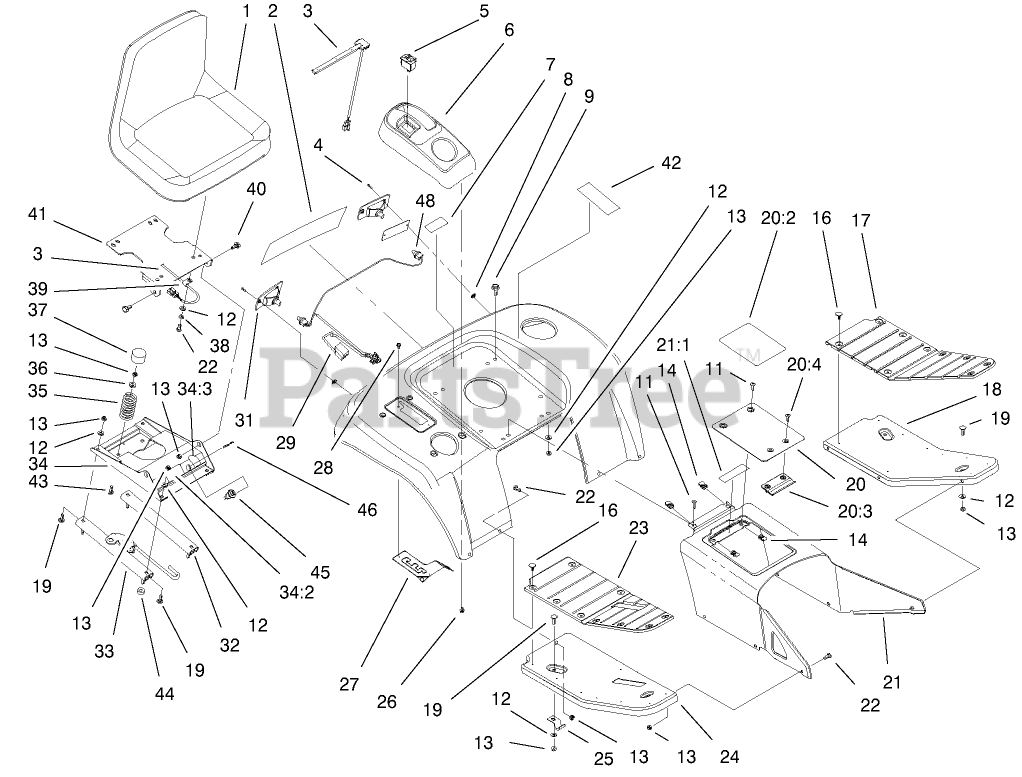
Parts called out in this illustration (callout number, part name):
3	SWITCH-SEAT
4	SCREW-PPH
5	SWITCH-CRUISE
6	POD-CONTROL
6	POD - CONTROL INT'L
7	DECAL - USA
8	NUT-SPEED
9	SCREW-HHF
11	SCREW-HH
12	WASHER-PLAIN
13	NUT-LOCK, NI
16	FASTENER-PANEL
17	PAD-FOOTREST, LH
18	FOOTREST-LH
19	SCREW-CARR
20	TUNNEL COVER ASM
20:2	DECAL-DANGER
20:2	DECAL - DANGER
20:3	RETAINER-COVER
20:4	SCREW-PPH
21	TUNNEL ASM
21:1	DECAL - WARNING
21:1	DECAL-DANGER
22	SCREW-HH
24	FOOTREST-RH
25	BRACKET-FOOTREST
26	SCREW-HWH
27	GATE-HI / LO SHIFT
28	SCREW-HWH
29	HARNESS-REAR
31	LAMP-TAILLIGHT
32	SLIDE-SLAVE, SEAT
33	SLIDE-LATCH, SEAT
34	SEAT BASE ASM
34:2	DECAL-DANGER
34:3	DECAL-SWITCH, NMIR
35	SPRING-COMPRESSION
36	BUSHING
37	CAP-SPRING, SEAT
38	WASHER-LOCK
39	CLAMP-R
40	BOLT-SHOULDER,HFH
42	DECAL - DIESEL
43	SCREW-CARR
44	WASHER-FLAT
45	STARTER SWITCH ASM
46	KEY-IGNITION
48	LIGHT BULB
